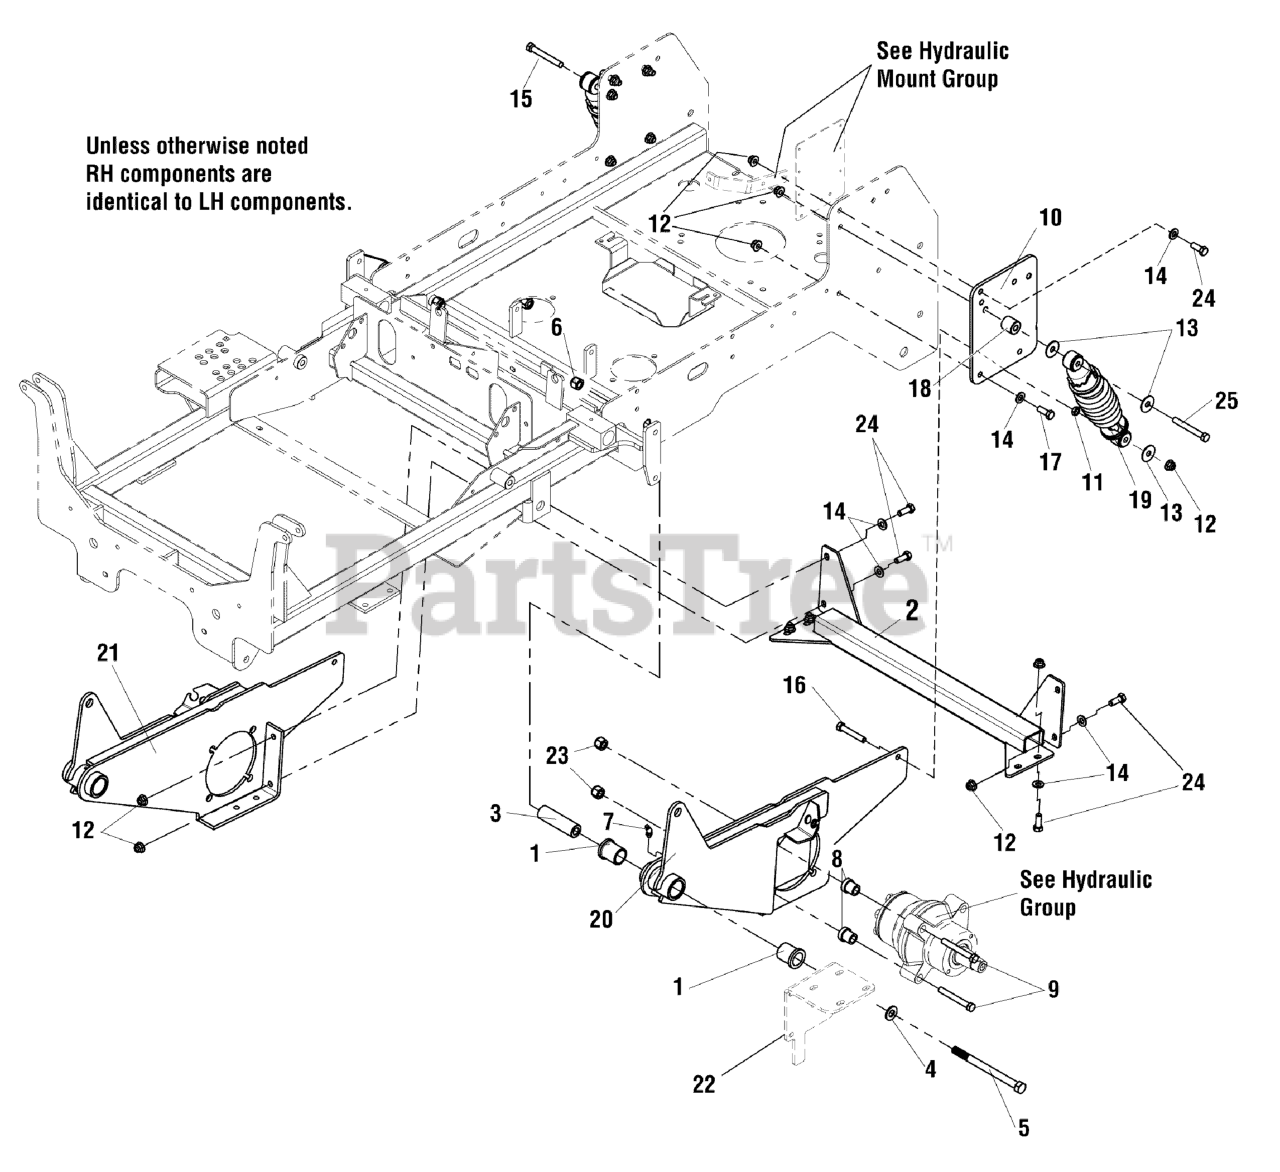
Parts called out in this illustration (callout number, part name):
1	BUSHING, FLANGE
2	KIT, TIE BAR, 61
3	SPACER, .52 X 1.00 X 3.42
4	WASHER, 1/2 GD9 YZ
5	BOLT, 1/2-13 X 6-1/2 GD8 YZ
6	NUT, 1/2-13 HEX NYLON LOCK
7	GREASE FITTING, 1/4-28 STRAIGHT
8	SPACER, .53 X 1.00 X 1.00
8	SPACER, .53 X 1.25 X 1.00, STEP, YZ
9	BOLT, 1/2-13 X 3-1/2, HEX HD, GD5, CZ (SV)
9	BOLT, 1/2-13 X 3.5, DRI-LOC PATCH
10	PLATE, FRAME SUPPORT, LH - RED
11	SPACER, .39 X 1.00 X .50
12	NUT, 3/8-16 HEX NYLOCK FLANGE
13	WASHER-3/8 FENDER
14	WASHER, 3/8 GD.9 FLAT
15	BOLT, 3/8-16 X 3" GD5 CZ
16	BOLT, 3/8-16 X 2-1/4" GD5 CZ
17	BOLT, 3/8-16 X 1" GD5 CZ
18	SPACER, .390 X 1.00 X 1.00 - YZ
19	SHOCK ABSORBER
20	WELD, MOTOR MOUNT - LH - RED
21	WELD, MOTOR MOUNT - RH - RED
22	FUEL TANK MOUNT (SEE FUEL TANK & MOUNT GROUP)
23	NUT, Hex Flange, Nylock, 1/2-13
23	NUT, 1/2-13 SQUARE
24	BOLT, 3/8-16 X 1-1/4" GD5 CZ
25	BOLT, 3/8-16 X 3-1/2" GD5 CZ
